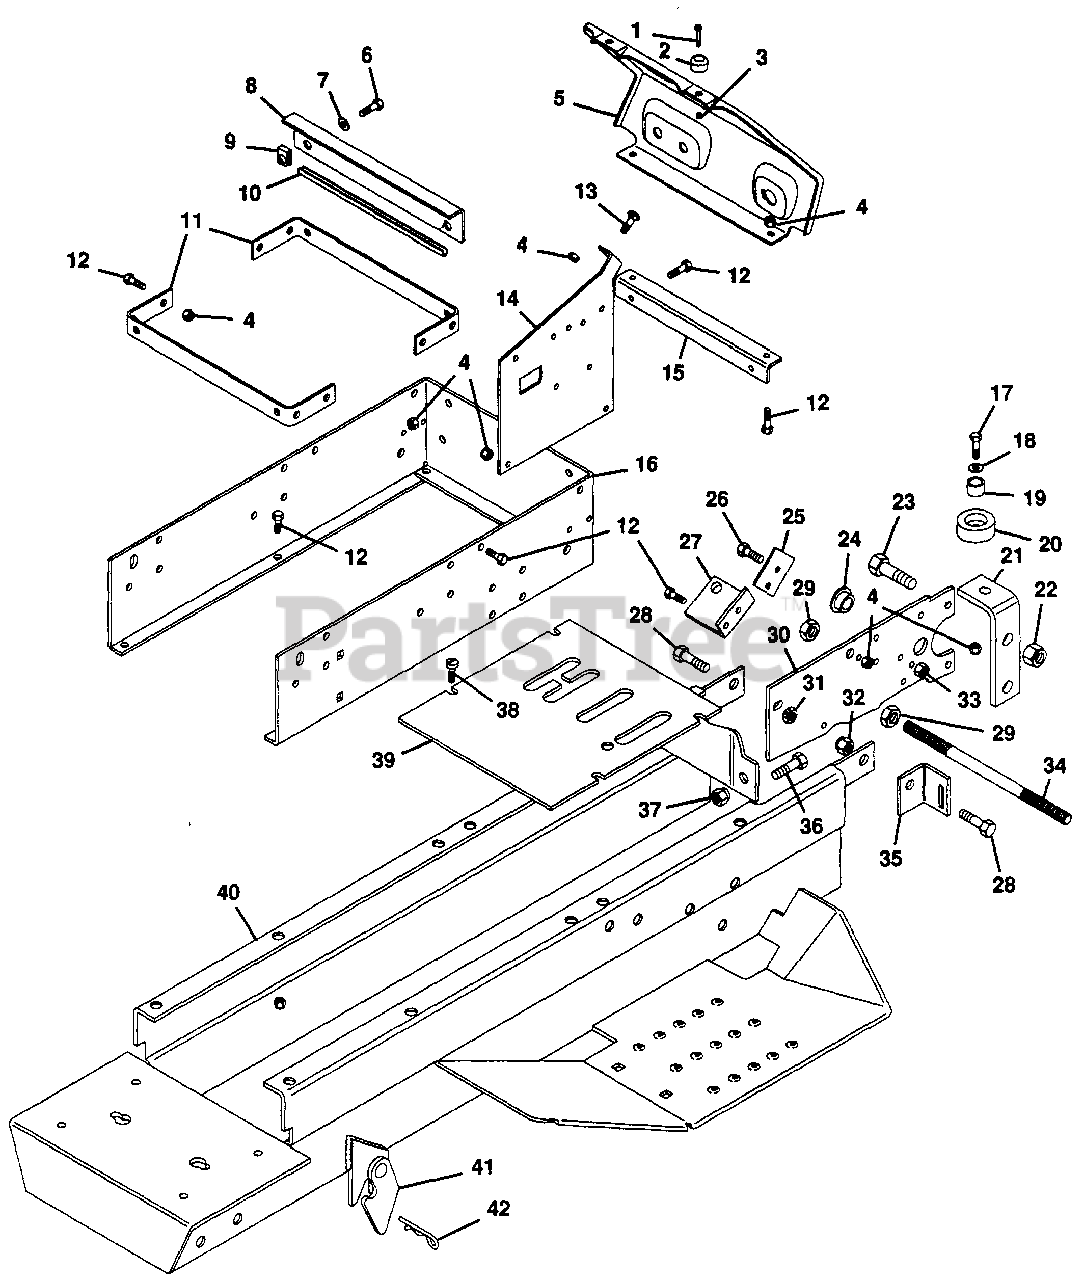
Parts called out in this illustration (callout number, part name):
1	SCREW, MACHINE 6-32X.625 PHD
2	BUMPER
3	NUT, MACHINE LOCK 6-32
4	NUT LOCK 1/4-20
5	PANEL, INSTRUMENT
6	BOLT, HEX 1/4-20X.875
7	WASHER, FLAT .281X.625X.065
8	BRACKET, FORWARD TANK
9	NUT, RETAINER
10	MOULDING
11	BRACKET, FUEL TANK
12	BOLT, HEX 1/4-20X.75
13	SCREW, MACHINE 1/4-20X.75 PHD
14	BRACE, INSTRUMENT PANEL L.H.
14	BRACE, INSTRUMENT PANEL R.H.
15	BRACKET, INSTRUMENT PANEL
16	SUPPORT, INSTRUMENT PANEL
17	BOLT, HEX 1/4-20X1.25
18	WASHER, FLAT .312X.734X.065
19	BUSHING, .259X.375X.25
20	BUMPER, SEAT
21	BRACKET, REAR HITCH
22	NUT, LOCK 1/2-13
23	BOLT, HEX 1/2-13X1.50
24	BUSHING, NYLON .76X1.00X.76 FLG
25	BRACKET, BUSHING LOCK
26	BOLT, HEX 5/16-18X.75
27	BRACKET, INTERLOCK SWITCH
28	BOLT, HEX 3/8-16X1.25
29	NUT, HEX 1/2-13
30	PLATE, FWD-REV MOUNTING
31	NUT, LOCK 3/8-16
32	NUT, LOCK 3/8-16
33	NUT, LOCK 5/16-18
34	ROD, FRAME EXTENSION BRACE
35	BRACKET, FENDER HOLD-UP
36	BOLT, HEX 1/2-20X1.50
37	NUT, RIM
38	SCREW, TAPPING 1/4-20X.625 PHD
39	PLATE, MANUAL CONTROL COVER
39	PLATE, HYDRAULIC CONTROL COVER
40	WELDMENT, FRAME
41	WELDMENT, MOWER BRACKET R.H.
41	WELDMENT, MOWER BRACKET L.H.
42	PIN, HAIR
